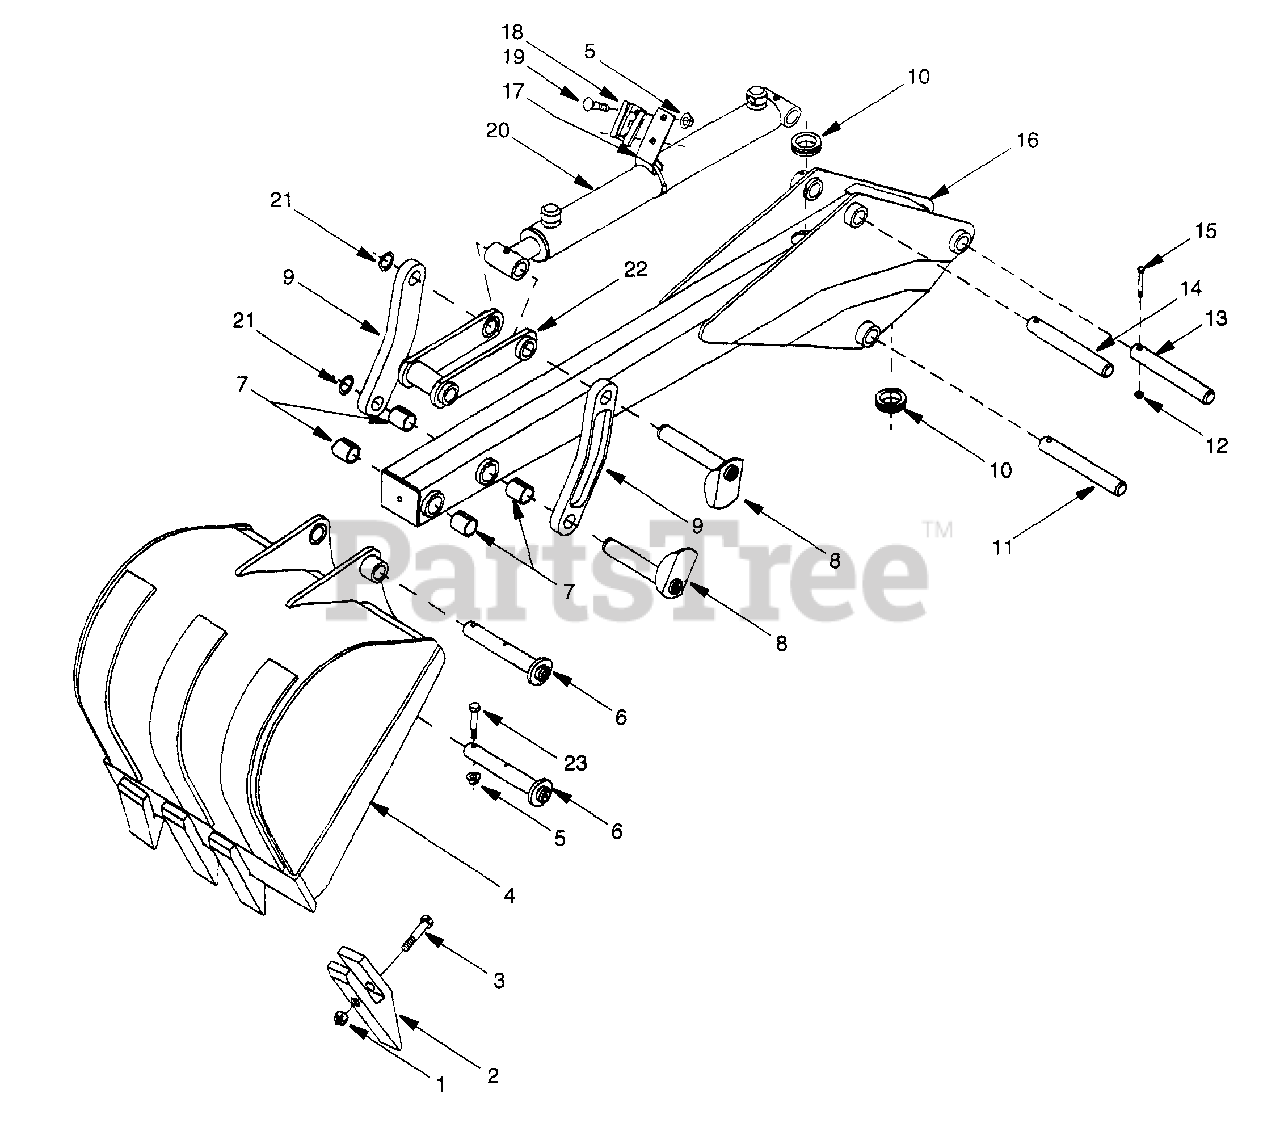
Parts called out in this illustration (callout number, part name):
1	Hex Locknut, 7/16 NC
2	Shank, 7.5 x 1.9375
4	8" Bucket, BH7500
5	Flange Hex Locknut, 5/16 NC
6	Clevis Pin, 1.0 x 5.77
7	Tension Bushing, 1 x 1.25 x 1.5
8	Clevis Pin, 1.0 x 5.81
9	Guide Link, 1.00 Dia. x 9.00
10	Grommet, .19 x 1.5 x 1.75
11	Pin, 1.0 x 7.3 x 7.69
12	Hex Locknut, 1/4 NC
13	Pin, 1.0 x 4.86 x 5.31
14	Pin, 1.0 x 5.23 x 5.69
15	Hex Hd Cap Screw, 1/4 NC x 2.5 GR8
16	Dipperstick
17	Bracket Socket, SMV
18	Socket, SMV Emblem
19	Carriage Bolt, 5/16 NC x 1/2
20	Hyd Cylinder, Double Acting 2 x 16.75
21	External Retaining Ring, .042 x .925
22	Bucket Link
23	Hex Hd Cap Screw, 5/16 x 2.5 GR5
